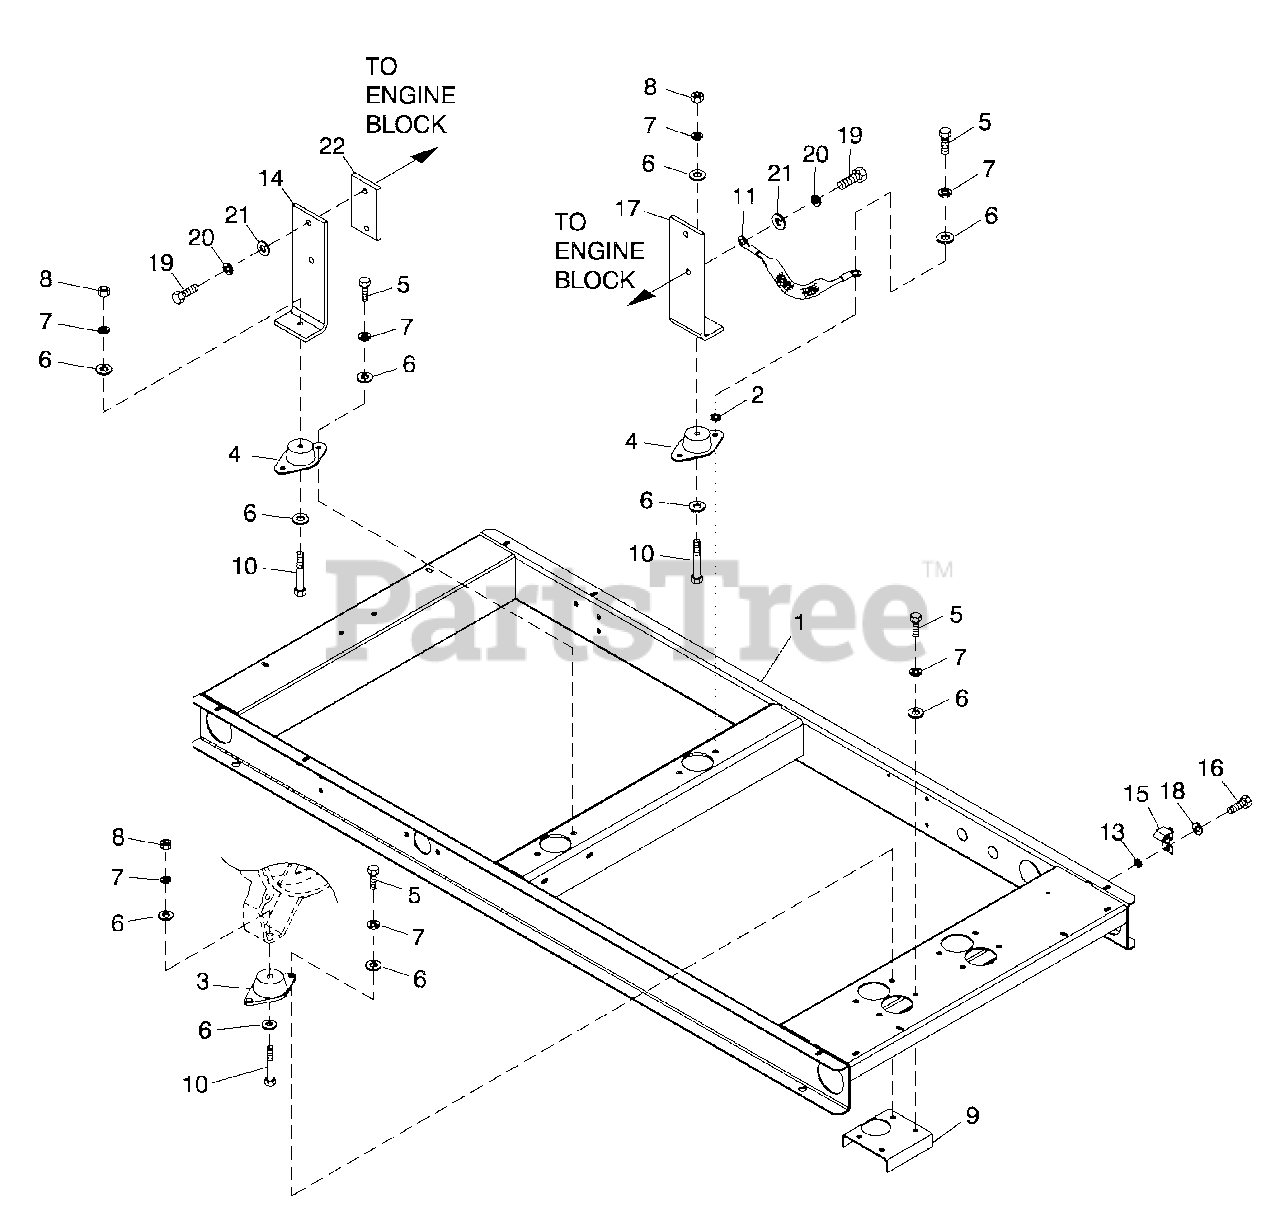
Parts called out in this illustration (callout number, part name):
1	MOUNTING BASE 2.4L
2	WASHER SHAKEPROOF EXT 5/16 STL
3	DAMPENER VIBRATION
4	VIB. ISO. 70-75 DURO
5	SCREW HHC M8-1.25 X 20 G8.8
6	WASHER FLAT 5/16 ZINC
7	WASHER LOCK M8-5/16
8	NUT HEX M8-1.25 G8 YEL CHR
9	ALTERNATOR SUPPORT BLOCK OFF
10	SCREW HHC M8-1.25 X 60 G8.8
11	EARTH STRAP
13	WASHER SHAKEPROOF EXT 1/4 STL
14	SUPPORT ENGINE LEFT SIDE
15	LUG SLDLSS #2-#8 X 17/64 CU
16	SCREW HHC M6-1.0 X 16 G8.8
17	SUPPORT ENGINE RIGHT SIDE
18	WASHER FLAT 1/4-M6 ZINC
19	SCREW HHC M10-1.25 X 30 C8.8
20	WASHER LOCK M10
21	WASHER FLAT 3/8-M10 ZINC
22	SPACER LH ENGINE MOUNT
